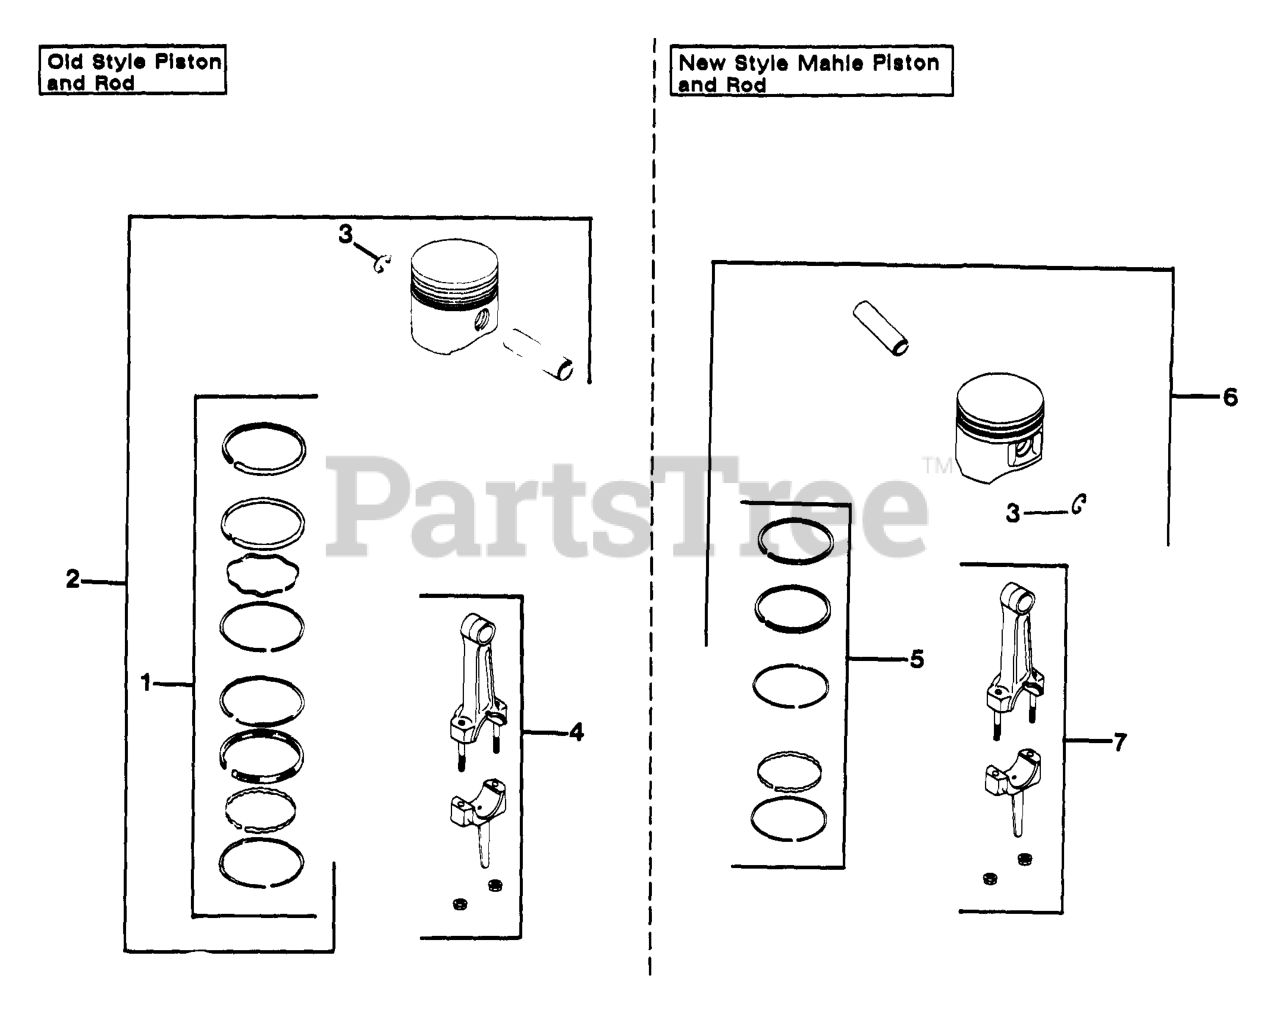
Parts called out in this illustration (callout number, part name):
1	RING SET - USE 48 108 01
1	RING SET - USE 48 108 02
1	RING SET - USE 48 108 03
1	RING SET - USE 48 108 04
2	KIT, PISTON W/RING SET STD
2	PISTON W/RING SET .003 - DISCONTINUED
2	PISTON W/RING SET .010
2	PISTON W/RING SET .020
2	PISTON W/RING SET .030
3	RETAINER
4	ROD STD. - DISCONTINUED
4	ROD .010 - DISCONTINUED
5	RINGS STD.
5	RINGS .010
5	RINGS .020
5	RINGS .030
6	KIT, PISTON W/RING SET STD - DISCONTINUED
6	PISTON W/RING SET .003 - DISCONTINUED
6	KIT, PISTON W/RING SET .010 - DISCONTINUED
6	PISTON W/RING SET .020
6	PISTON W/RING SET .030
7	ROD, STD
7	ROD .010
